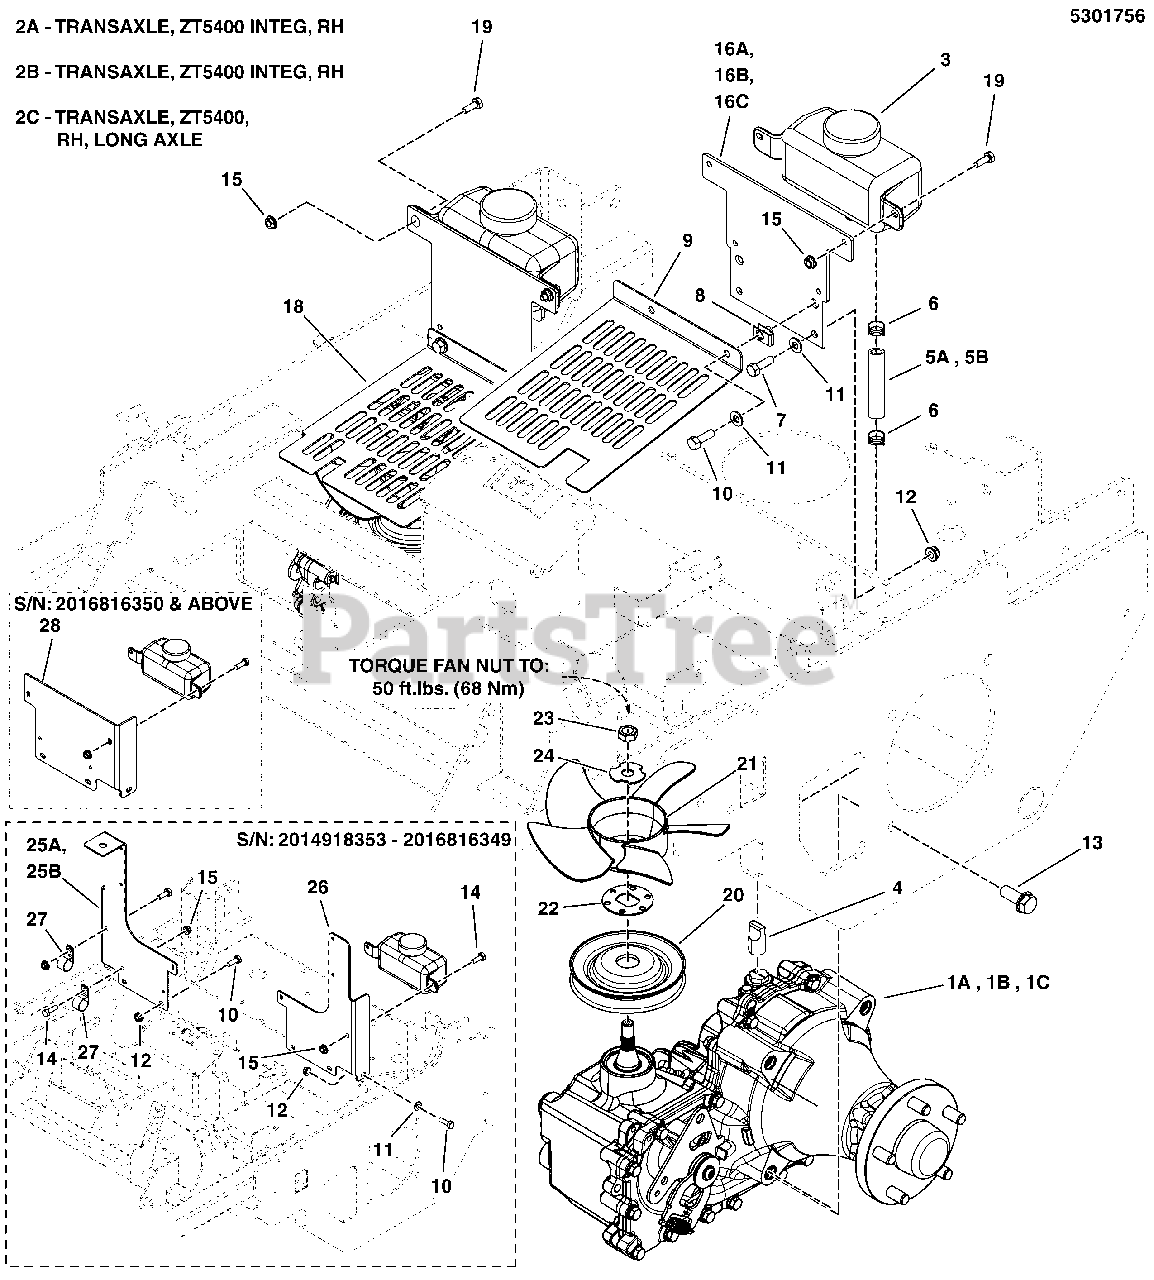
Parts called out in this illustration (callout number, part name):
1A	TRANSAXLE, ZT5400, LH, 1015-1024L
1B	TRANS, INTEGRATED, LH
1C	TRANSAXLE, ZT5400, LH, 1015-1057L L AXLE
2A	TRANSAXLE, ZT5400, RH, 1015-1024R
2B	TRANS, INTEGRATED, RH
2C	TRANSAXLE, ZT5400, RH, 1015-1057R L AXLE
3	HYDRO TANK, HYDRO-GEAR 71938, 1 LITER
4	FITTING, BREATHER, ZT5400
5A	HOSE, OFFSET FORMED
5B	HOSE, 5/8 PUSH-LOCK, 6.00"
6	CLAMP, #10 HOSE, STAINLESS
7	BOLT, 5/16-18 X 3/4 GD5
8	BODY CLIP, 5/16-18-7GA MATERIAL
9	GUARD, FAN, LH - RED
10	BOLT, 5/16-18 X 3/4 GD5
11	WASHER, 5/16" SAE
12	NUT, 5/16-18 HEX NYLOCK FLANGE NUT
13	BOLT,HEX FLG,SER,GD8 1/2-13X1-1/4W/PATCH
14	BOLT, 1/4-20 X 1" GD5 CZ
15	NUT, 1/4-20 Hex Nylock Flange
16A	PLATE, HYDRO TANK
16B	PLATE, HYDRO RES TANK - BLK
16C	PLATE, HYDRO TANK
18	GUARD, FAN, RH - RED
19	BOLT, 1/4"-20 X 3/4" GD5 YZ
25A	BRKT, HYD TNK/CARB CAN, S200XT RH - BLK
25B	BRACKET,HYD TANK, RH - BLK
26	BRACKET,HYD TANK, LH - BLK
27	CLAMP, VINYL INSULATED, 1.00
28	BRACKET, HYD TANK, S200XT, LH - BLK
